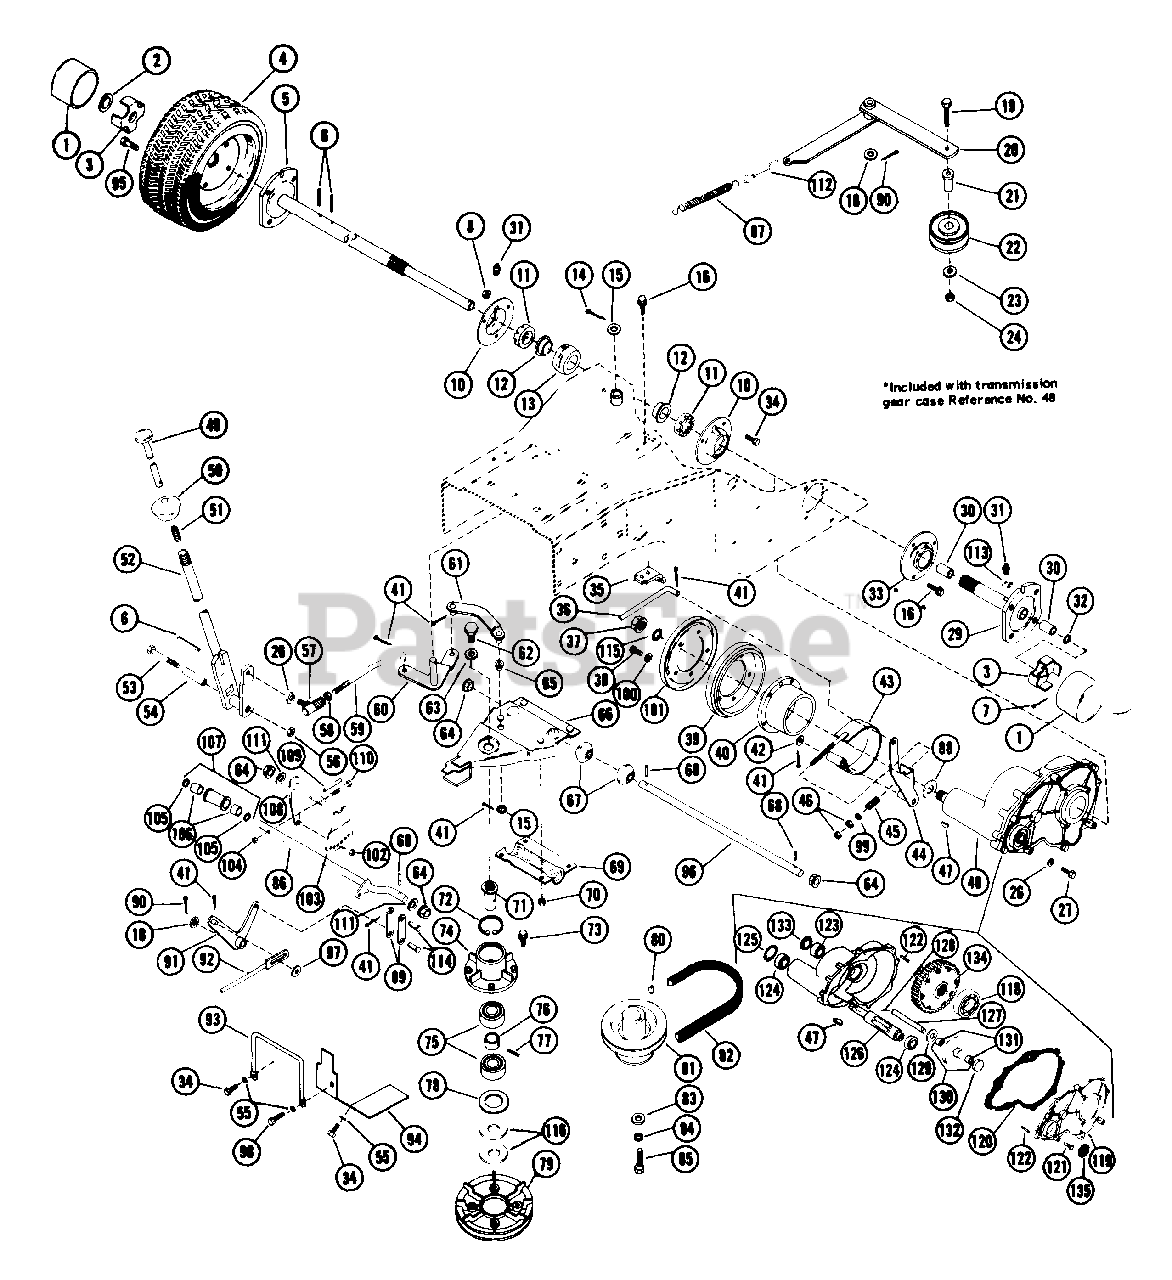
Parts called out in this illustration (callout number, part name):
1	HUB CAP
2	PUSHNUT
3	SPINDLE CUP
4	TERRA TIRE & WHEEL ASSEMBLY
5	R H AXLE SHAFT
6	PIN-ROLL .188X1.50
7	PIN-COTR .12 X 1.25 PL
8	NUT-LK-FLG .250-20 PL
10	BEARING FLANGE
11	ADJUSTMENT SPACER
12	BSHG-FLG 1.125X1.31X.50X1.62BR
13	SPHERICAL BUSHING
14	PIN-COTR .12X1.0 PL
15	WSHR-FL-STL .505X.880X.072 PL
16	BLT-SCRHFWH .25-20X.62 PL
18	WSHR-FL-STL .505X1.000X.062
19	BLT-HEX .31-18X1.25 PL GR2
21	SPCR, BRG .315X.50X.688X.281
22	IDLER
23	WSHR-FL-STL .38X.875X.083 PL
24	NUT-LK .312-18 GR A PL
26	WSHR-LK .312X.097 PL HVY
27	BLT-HEX .31-18X1.50 PL GR2
29	L H AXLE ASSEMBLY
30	BSHG-SLV .750X.814X .750 BRZ
31	SPIN DRIVE ZERK FITTING
32	O-RING .755X.950X.097
33	SEAL 1.125X2.496X.380
34	BLT-HEX .25-20X.50 PL GR2
35	NEUTRAL STOP
36	BRAKE ROD
37	NUT-LK-NYL.625-18 PL
38	BLT-HEX .31-18X.50 PL GR2
39	FRICTION DISC
40	FRICTION DISC HUB
41	PIN-COTR .09X.75 PL
42	WSHR-FL-STL .380X.626X.033
43	BRAKE BAND
44	BRAKE LEVER
45	SG-COMP .105X.585X.75
46	NUT-HEX .312-18
47	KEY-WDRF .188X.875X.375 SAE11
48	GEAR CASE ASSEMBLY
49	SHIFT CONTROL ROD
50	SHIFT BALL
51	SG-COMP ??X.44X?? WLD 10
52	SHIFT LEVER
53	BLT-HEX .38-16X2.50 PL GR2
54	SHIFT SPACER
55	WSHR-LK .250X.077 HVY PL
56	NUT-LK-CTR .375-16 GR A PL
57	SNAP IN BALL JOINT
58	NUT-HEX .312-24 PL
59	SHIFT ROD
60	SHIFT LEVER
61	SHIFT LINK
62	SPINDLE STUD
63	WSHR-LK-EXT .500X.040 MED
64	FLANGE BUSHING
65	BSHG-FLG .372X.500X.312X.625NY
66	MTG PLATE
67	BEARING
68	PIN-ROLL .188X1.13
69	BEARING RETAINER
70	NUT-LK-CTR .250-20 PL
71	SPINDLE
72	SNAP RING KIT
73	BLT-SERHFWH .25-20X.75 PL
74	SPINDLE HOUSING
75	BRG-BALL .751X1.78X.61
76	SPACER .753X1.000X.457
77	PIN-ROLL .188X1.00
78	WSHR-FL-STL 1.375X2.125X.075
80	KEY-STR .25X2.0X.25
81	SHEAVE
82	V-BELT, SAE 380-RAW EDGE
83	WSHR-FL-STL .438X1.125X.19
84	WSHR-LK .375X.115 HVY PL
85	BLT-HEX .38-24X1.25 BLKO GR5
87	SG-TENS 5.65 FREE LENGTH
88	WSHR-FL-STL .627X.990X.032
89	LINK PLATE
90	PIN-COTR .09X1.0 PL
91	CLUTCH LEVER
92	CLUTCH ROD
93	BELT GUIDE
94	SPLASH GUARD
95	BLT-WHL .50-20X.75 GR5 PL
96	HINGE SHAFT
97	WSHR-FL-STL .382X.812X.023 PL
98	BLT-HEX .25-20X.75 PL GR2
99	WSHR-FL-STL .323X.625X.062 PL
100	WSHR-LK-INT .313X.030 PL
102	NUT-KEPS 8-32
103	STOP ADJUSTMENT
104	NUT-LK TOP .250-20 PL
105	SEAL .625X.875X.125
106	BSHG-SLV .625X.750X.500 BR
107	ROLLER ASSEMBLY
109	PIN-GRV .250X1.25 TP A
110	BLT-HEX .25-20X1.50
111	WSHR-FL-STL .630X1.005X.062 PL
112	SPRING HOOK
113	WSHR-LK .250X.047 LT PL
114	CLEVIS PIN
115	WSHR-LK-INT .625X.045 PL
116	WSHR-FL-STL 2.125X1.375X.005
117	COVER & CASE ASSEMBLY
118	BRG-BALL 1.125X2.50X.63
119	BREATHER
121	SCR-TAP 10-24X.75 HWH PL TR
122	PIN-GRV .188X.63
123	BSHG-SLV 1.125X1.375X.625
124	BRG-BALL .625X1.375X.44
125	RG-RTNG-INT 1.375X.050
126	PINION SHAFT
127	IDLER SHAFT
128	PIN-ROLL .125X.75
129	WSHR-FL-STL .505X1.000X.062
130	PINION & GEAR W/BEARING ASSEMB
131	BRG-NEEDLE .50X.688X.625
132	SPACER .507X.875X.289
133	SEAL 1.125X1.624X.250
134	DIFFERENTIAL ASSEMBLY
